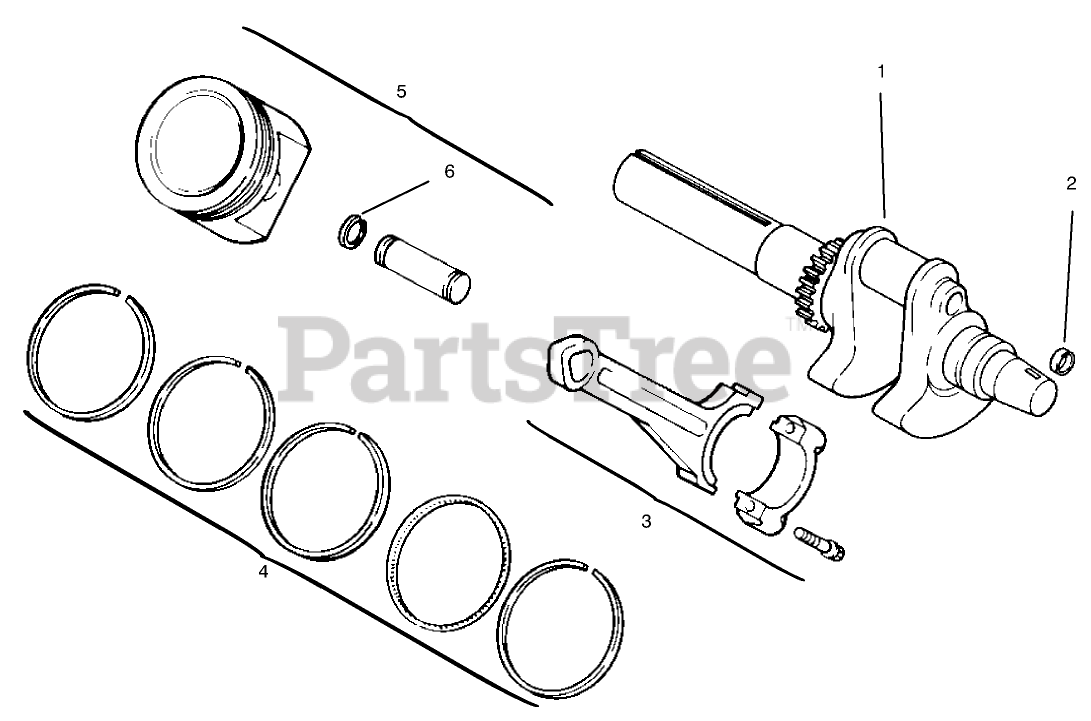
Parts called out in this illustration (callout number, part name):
1	Crankshaft
3	Connecting Rod (Std.)
4	Set-Ring (STD)
5	Piston w/Ring Set (Std.)(Incl. Ref. # 4-6)
6	RETAINER-PIN, PISTON
